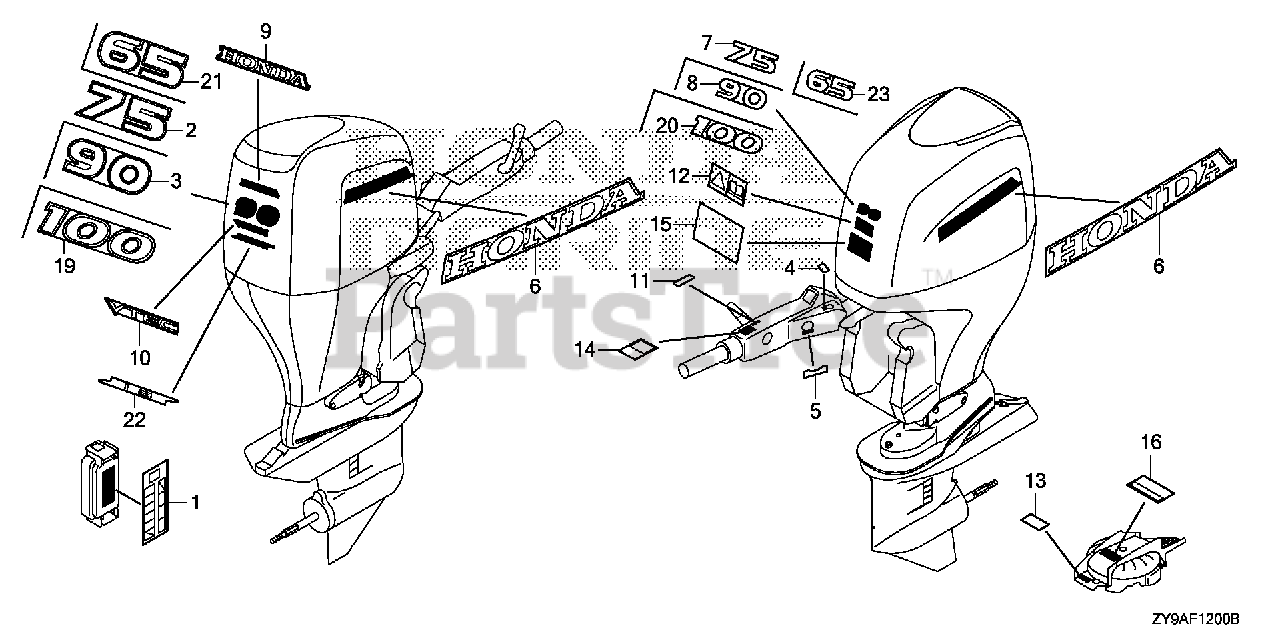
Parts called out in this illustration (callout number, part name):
1	LABEL, FUSE
3	MARK, RR. (90)
6	MARK, SIDE STRIPE
8	MARK, FR. EMBLEM (90)
9	MARK, HONDA
10	MARK (VTEC)
13	LABEL, CAUTION OIL (ENGLISH)
15	LABEL, CAUTION OPERATOR (ENGLISH)
16	MARK, EMERGENCY START (ENGLISH)
